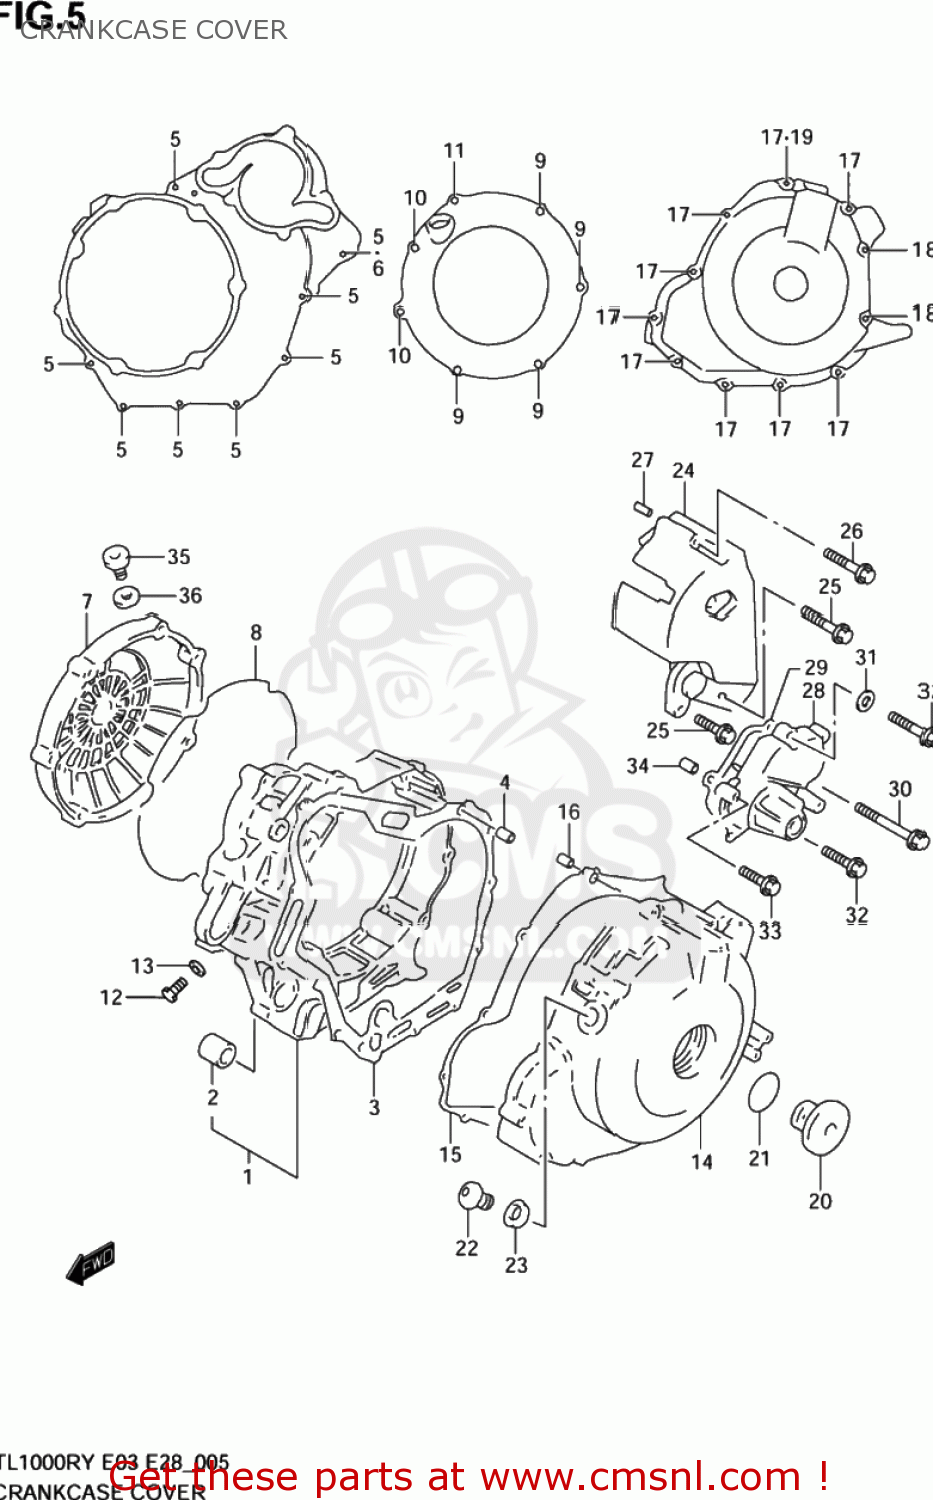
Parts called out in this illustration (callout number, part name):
1	COVER,CLUTCH
2	LENS,OIL LEVEL CHECK
3	GASKET,CLUTCH COVER (NAS)
4	PIN
5	BOLT,G/S SWITC
6	GASKET(5.8X13X1.2) (NAS)
7	COVER,CLUTCH OUTER
8	O RING,CLUTCH COVER OUTER
9	BOLT(6X30)
10	BOLT(6X75)
11	BOLT(6X85)
12	BOLT
13	GASKET(6.2X11X1).2 (NAS)
14	COVER,MAGNETO
15	GASKET,MAGNETO COVER (NAS)
16	PIN
17	BOLT(6X35)
18	BOLT(6X70)
19	GASKET(5.8X13X1.2) (NAS)
20	PLUG
21	O RING(D:3.1,ID:32.7)
22	PLUG
23	GASKET(13.8X18.8X4.8) (NAS)
24	COVER,ENGINE SPROCKET
25	BOLT(6X35)
26	BOLT(6X70)
27	PIN
28	COVER,GEAR SHIFT
29	GASKET,GEAR SHIFT COVER (NAS)
30	BOLT(6X105)
31	GASKET(5.8X13X1.2) (NAS)
32	BOLT
33	BOLT
34	PIN
35	PLUG
36	O RING(D:3.1,ID:16.8)
